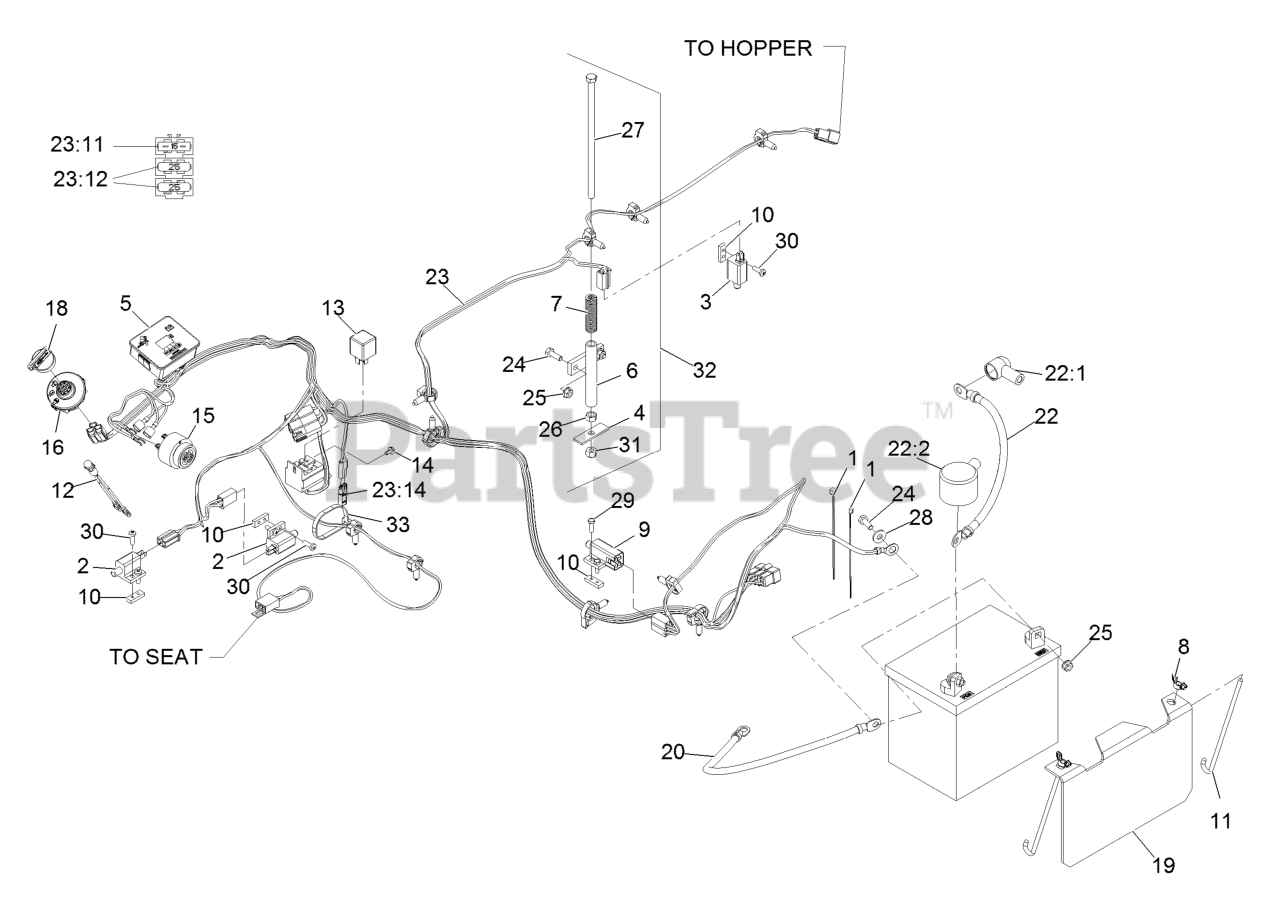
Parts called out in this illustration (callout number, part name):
1	TIE-CABLE
2	SWITCH-OPEN, NORMALLY
3	SWITCH-CLOSED, NORMALLY
4	PLATE-SWITCH, SEAT
5	HOUR METER ASM
6	MOUNT-SPRING, SEAT
7	SPRING-SWITCH, SEAT
8	WINGNUT
10	PLATE-TAPPED
11	BOLT-HOLDDOWN
12	INDICATOR-LED, RED
14	SCREW-HWH
15	ALARM-TONE, DUAL
18	KEY-IGNITION
19	HOLD DOWN-BATTERY
20	CABLE-BATTERY, NEGATIVE
22	CABLE-BATTERY, POSITIVE
22:1	INSULATOR-SOLENOID
22:2	INSULATOR-BATTERY
23	HARNESS-WIRING
23:11	FUSE-BLADE, 15 AMP
23:12	FUSE-BLADE, 25 AMP
23:14	CAP-PLUG
24	SCREW-HH
26	NUT-HEX
27	SCREW-HH
28	WASHER-FLAT
30	SCREW-PPH
31	NUT-LOCK, NI
32	HOPPER SWITCH ACTUATOR AS
33	TIE-PLASTIC
